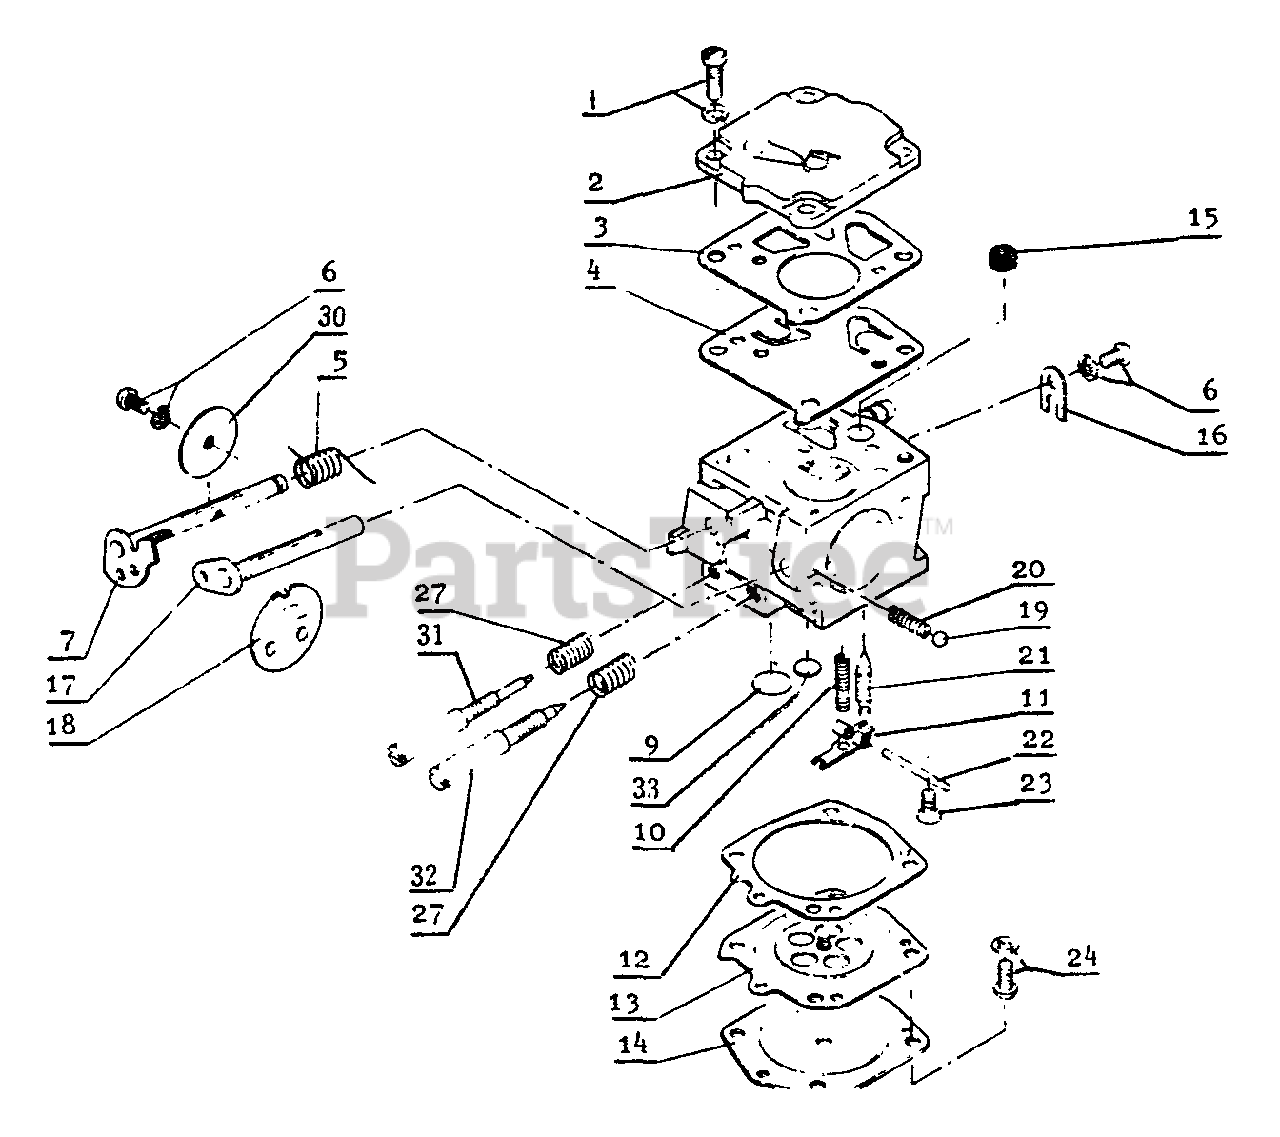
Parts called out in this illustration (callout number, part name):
1	SCREW
2	COVER, PUMP
3	GASKET, PUMP
4	DIAPHRAGM, PUMP
5	SPRING, RETURN
6	SCREW
7	SHAFT, THROTTLE
9	PLUG, WELCH - LARGE
10	SPRING, METERING LEVER
11	LEVER, METERING
12	GASKET, DIAPHRAGM
13	DIAPHRAGM
14	COVER, DIAPHRAGM
15	STRAINER
16	RING, RETAINING
17	SHAFT, CHOKE
18	VALVE, CHOKE
19	BALL, CHOKE SET
20	SPRING, CHOKE SET
21	VALVE, INLET NEEDLE
22	PIN, METERING LEVER
23	SCREW, METERING LEVER PIN
24	SCREW
27	SCREW, IDLE ADJUST
30	VALVE, THROTTLE
31	SCREW, IDLE ADJUST
32	SCREW, MAIN ADJUST
33	PLUG, WELCH - SMALL
